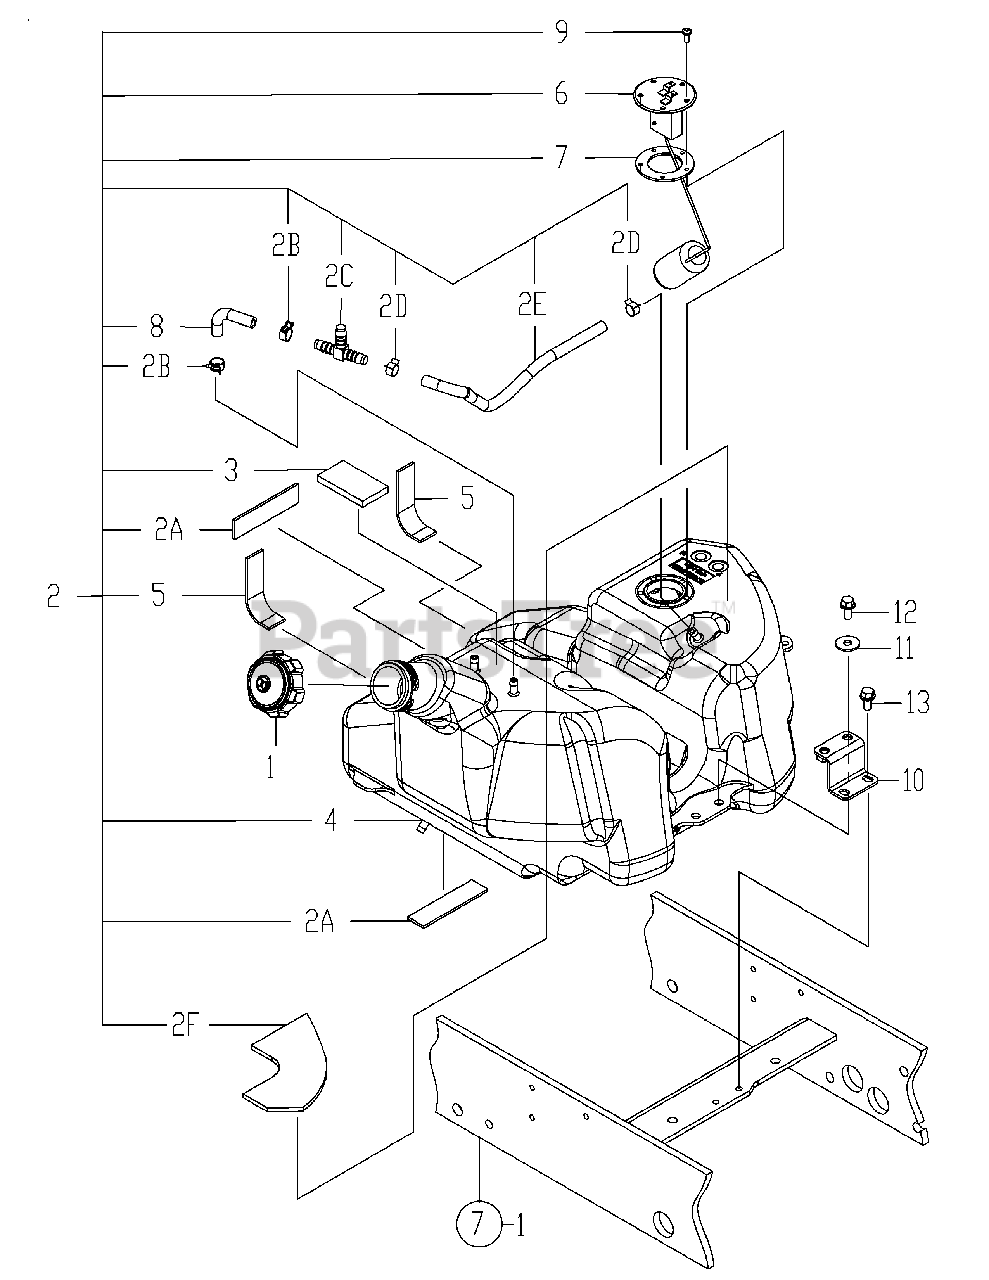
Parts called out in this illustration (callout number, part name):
1	CAP, FUEL TANK
2	TANK ASSY, FUEL
2A	RUBBER 100 X 25 X 3
2D	CLAMP, HOSE 12
2E	HOSE, 7.3 X 260
2F	CUSHION,FUEL TANK RH
3	CUSHION,FUEL TANK
4	TANK, FUEL
5	CUSHION, FUEL TANK SI
6	SENDER ASSY,FUEL
7	GASKET, FUEL GAUGE
